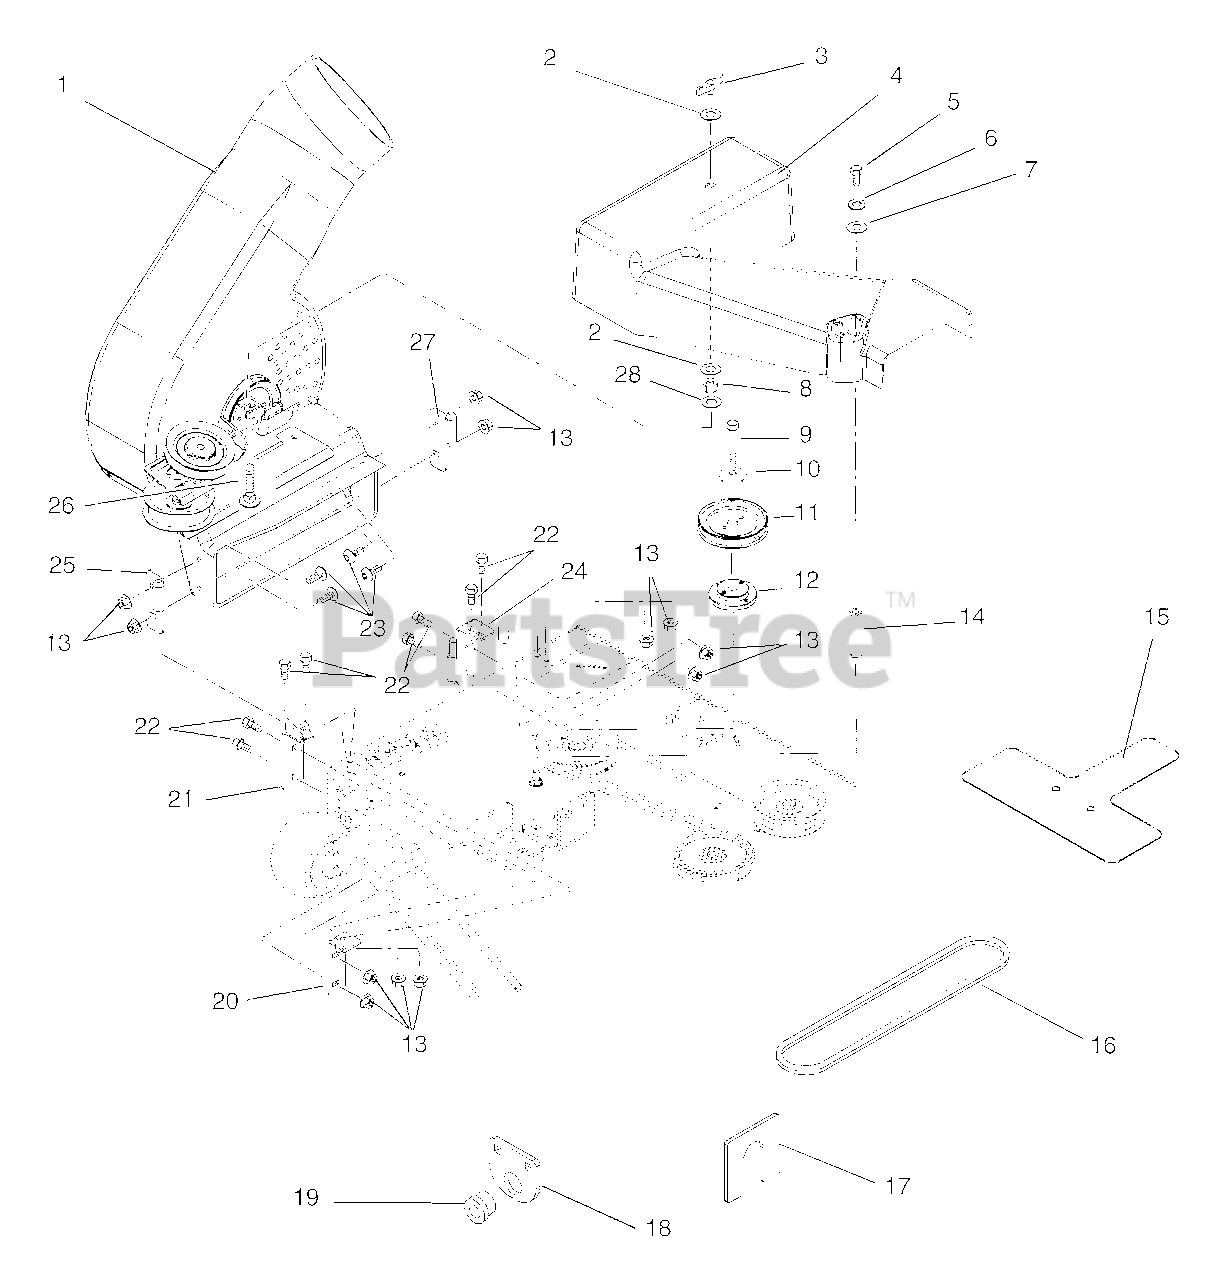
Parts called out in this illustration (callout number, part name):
1	Housing, Blower
2	Washer-Flat-Steel.38 x 1.50 x .062
3	Knob- Wing .312-18
4	Belt Cover
5	Bolt-Hex .38-16 x .75- Grade 5
6	Washer-Locking .38 x .094 Regular
7	Washer-Flat-Steel .438 x 1.00 x .083
8	Nut-Jam .312-18
9	Bolt-Hex .38-16 x 1.75- Grade 8
10	Washer, Cupped, .375 (comes with mower deck)
11	Sheave, 3.00 Diameter (40- and 44-inch Mower Decks)
11	Sheave, 4.00 Diameter (48- and 52-inch Mower Decks)
12	Assembly, Sheave Adapter
13	Nut-Locking-Top-Flange .25-20
14	Spacer, Cover
15	Guard, Finger (40-Inch Mower Decks)
16	V-Belt (40- and 44-Inch Mower Decks)
16	V-Belt (48- and 52-Inch Mower Decks)
17	Lift Plate
18	Bracket,Rear Pivot
19	Bushing-Flange 1.000 x 1.12 x .62 x 1.50
20	Bracket, Front
21	Weldment, Front Mount Bracket
22	Bolt-Hex .25-20 x .75- Grade 5
23	Screw-Machine .25-20 x .75
24	Weldment, Rear Mount Bracket
25	Weldment, Housing Mount Right Hand
26	Bolt-Round Head Square Neck .31-18 x 1.50
27	Weldment, Housing Mount Left Hand
28	Washer-Flat-STL .312 x .734 x .065
